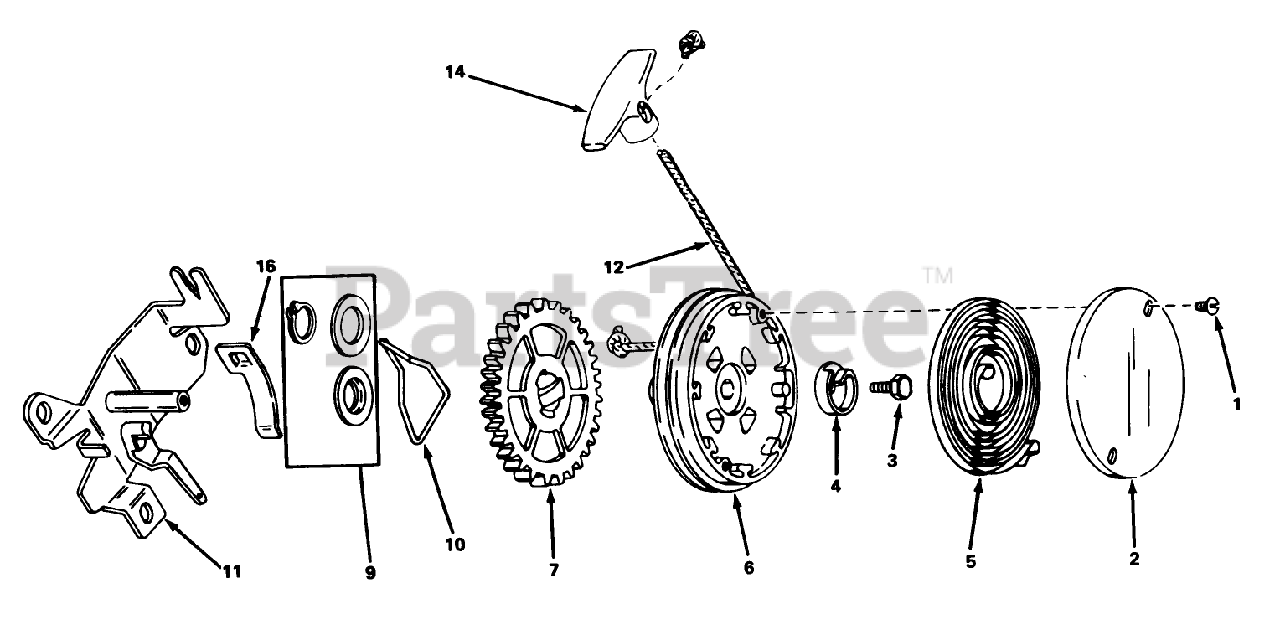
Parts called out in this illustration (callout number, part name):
1	Screw
2	Cover, Spring
3	Screw, Hex Washer Head
4	Hub Spring
5	Spring, Rewind
6	Pulley Assy. (Incl. No. 9)
9	Kit, Thrust Wash. Snap Rg.
10	Brake
11	Bracket Assy., Mounting
12	Rope-Starter
14	Handle-Starter
16	Clip Rope
